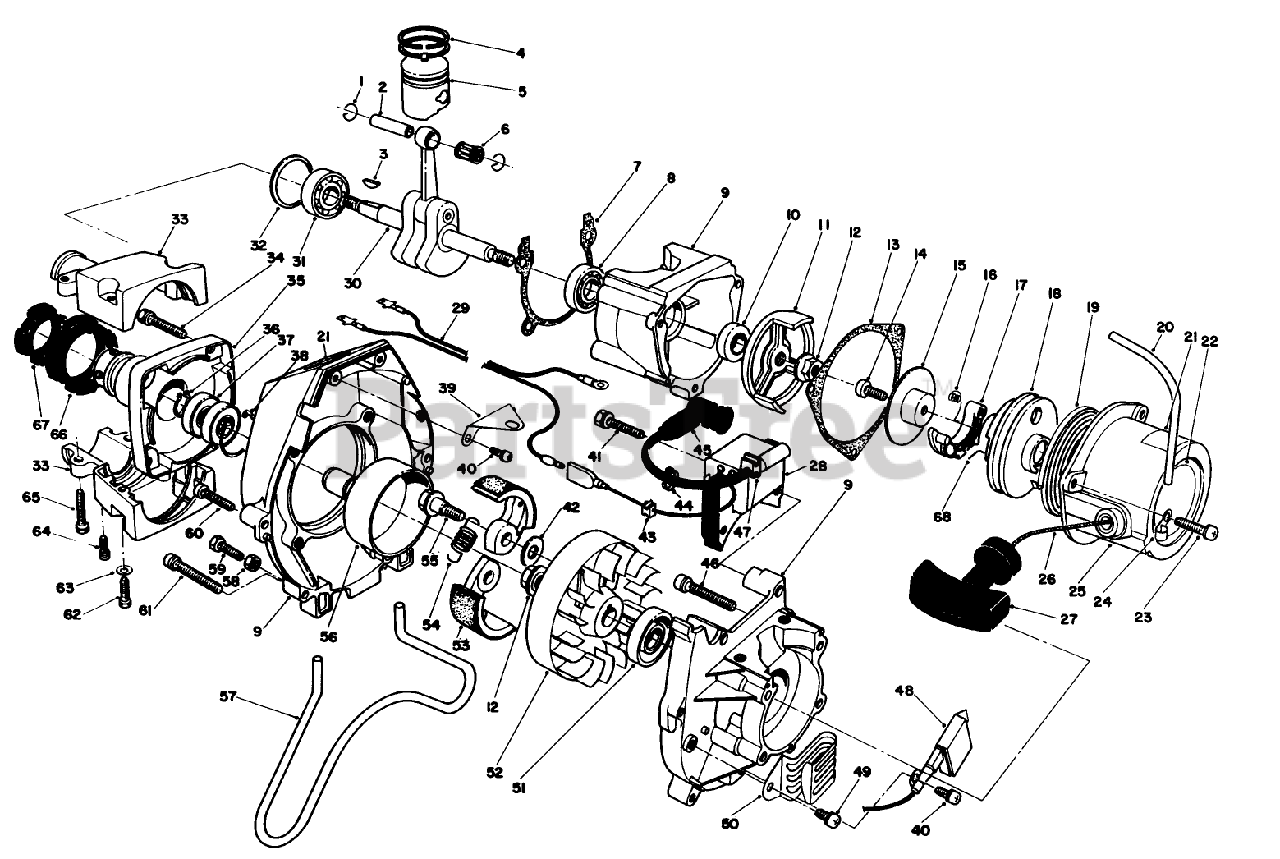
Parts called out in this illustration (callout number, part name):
1	PISTON PIN CLIP
4	PISTON RING
5	PISTON SET
8	BEARING
10	OIL SEAL
16	SPRING, RETURN
17	RATCHET
19	SPRING, SPIRAL
31	BALL BEARING
37	BALL BEARING
41	BOLT AND WASHER
45	CAP-PLUG
46	SCREW & WASHER
51	OIL SEAL
53	SHOE, CLUTCH
57	TANK GUARD
66	RUBBER, CUSHION (A)
67	RUBBER, CUSHION (B)
